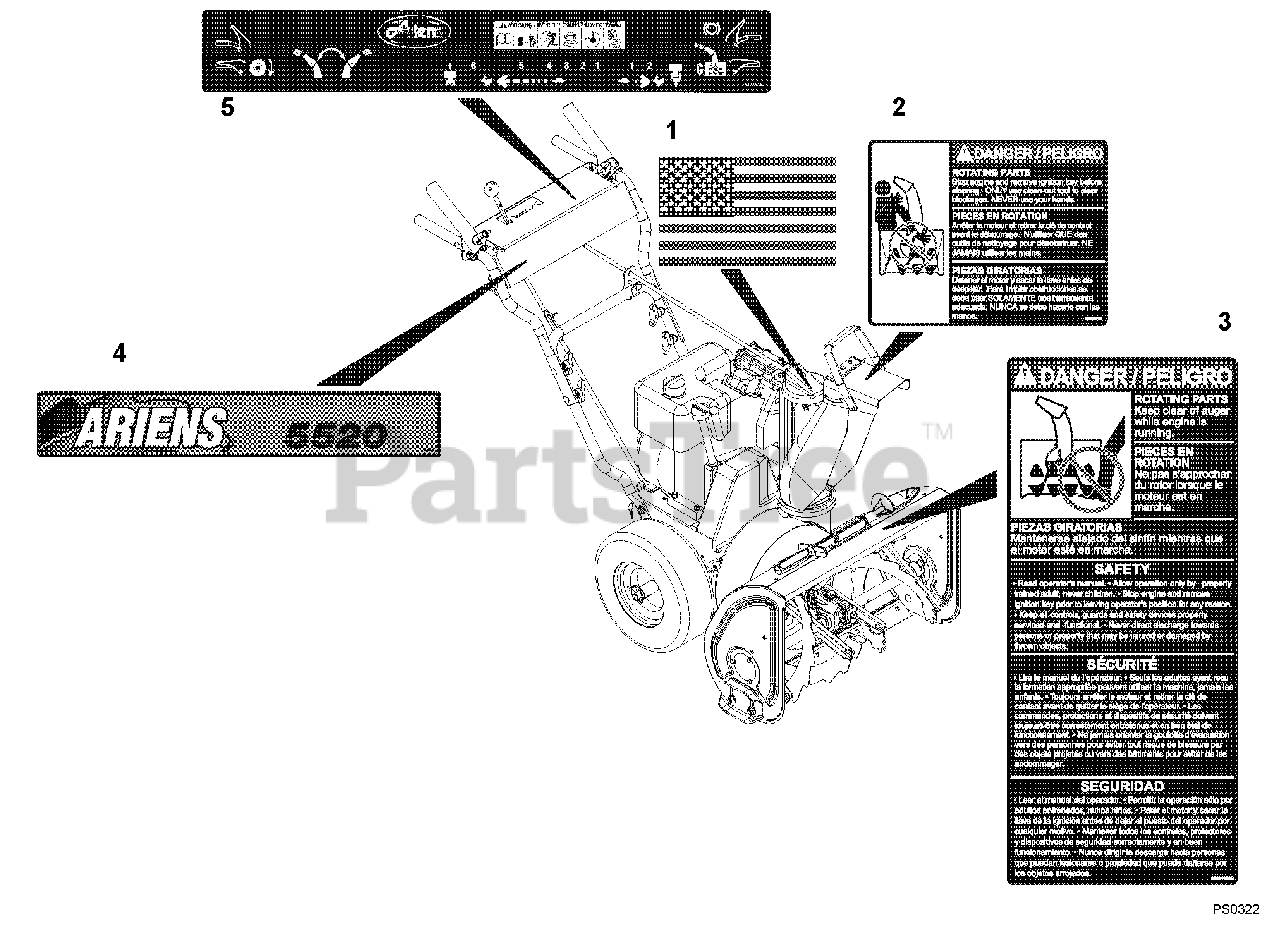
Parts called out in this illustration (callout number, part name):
1	DECAL, AMERICAN FLAG
2	DECAL, DANGER - ROT. PARTS
3	DECAL, DANGER
4	DECAL, FRONT PANEL 724
5	DECAL, DASH PANEL - COMPACT
